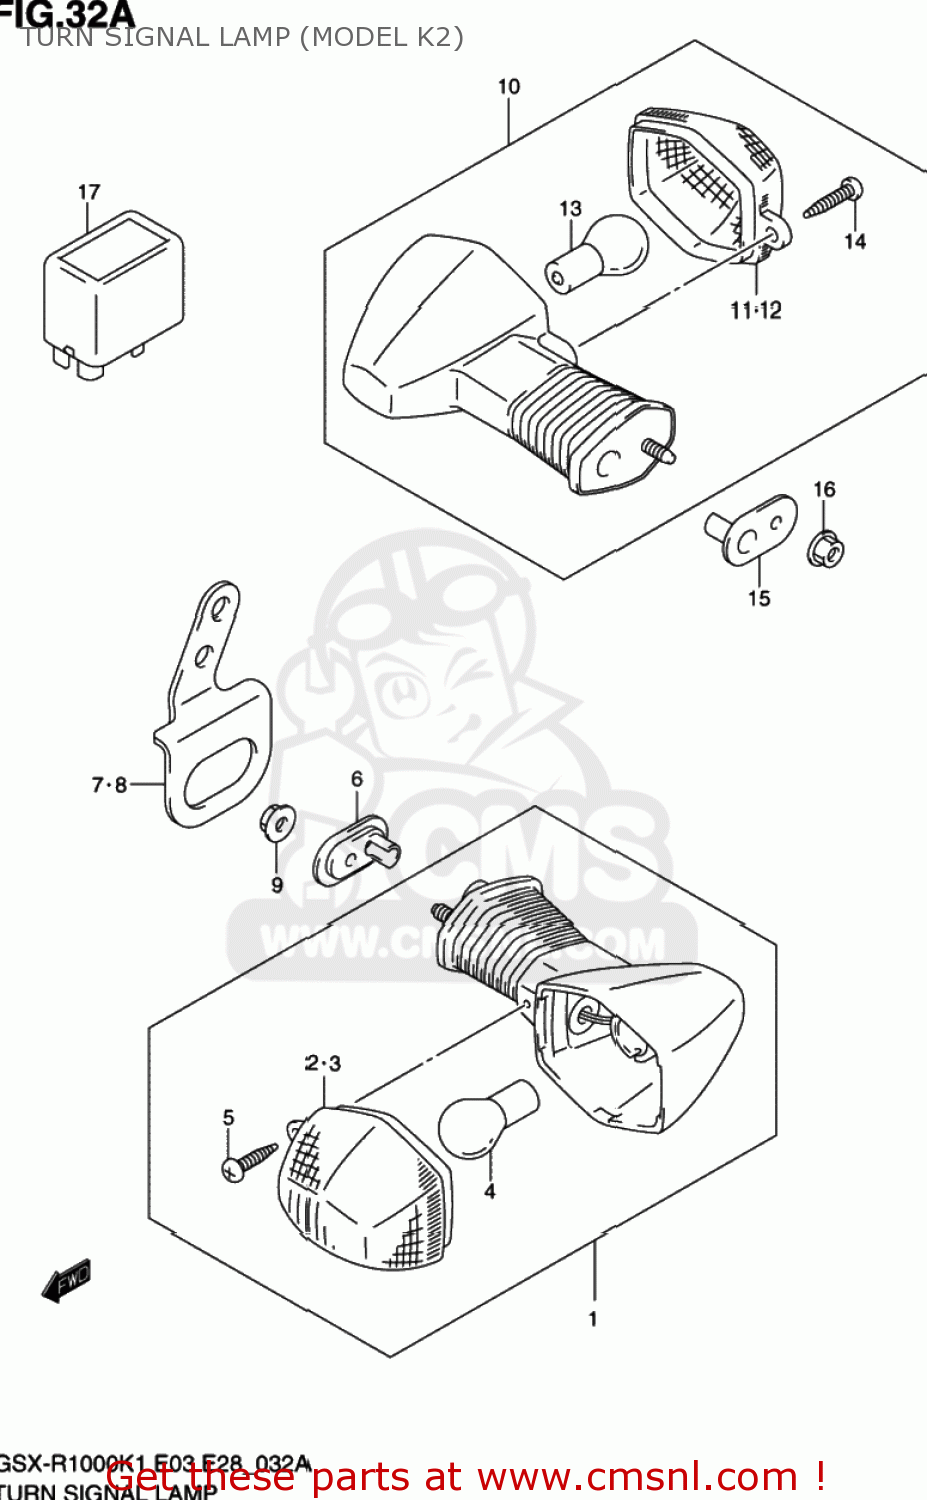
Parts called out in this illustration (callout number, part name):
1	LAMP ASSY,FR TURN SIGNAL,R
2	LENS
3	LENS
4	BULB(12V21W)
5	SCREW
6	PLATE,TURNSIGNAL LAMP
7	BRACKET,FR TURNSIGNAL,R
8	BRACKET,FR TURNSIGNAL,L
9	NUT
10	LAMP ASSY,RR TURNSIGNAL,R
11	LENS
12	LENS
13	BULB(12V21W)
14	SCREW
15	PLATE,TURNSIGNAL LAMP
16	NUT
17	RELAY ASSY,TURNSIGNAL LAMP
